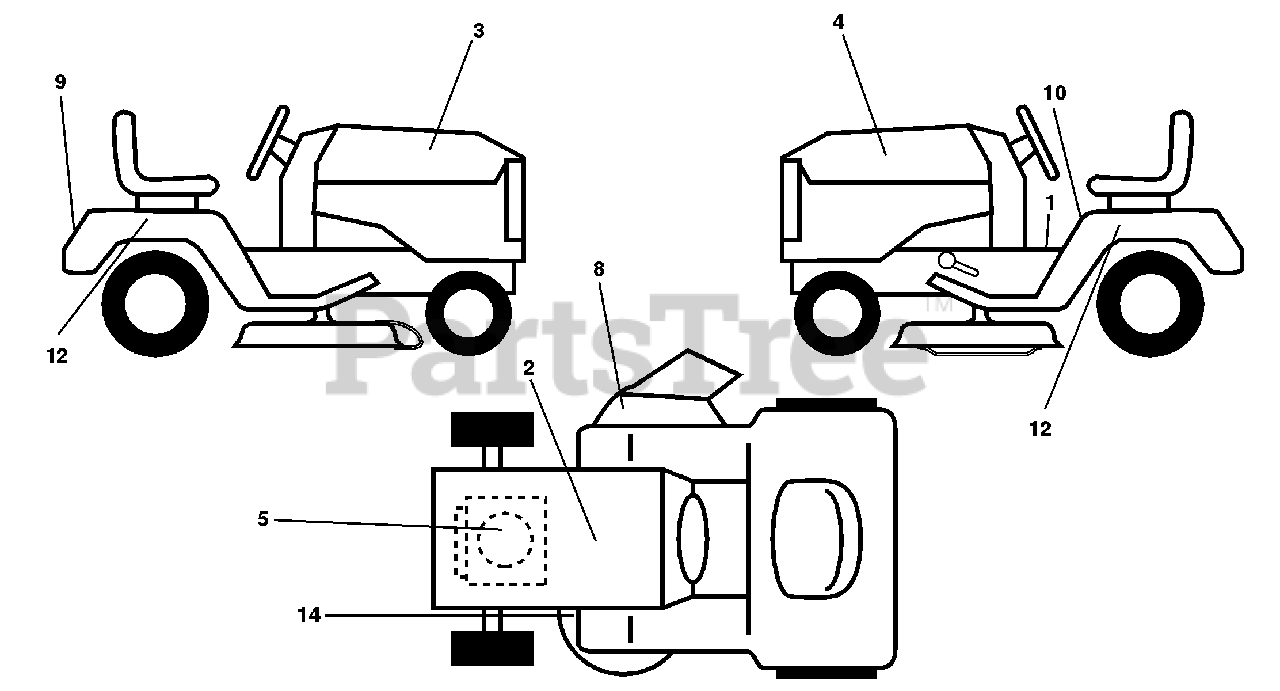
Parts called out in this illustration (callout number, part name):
1	Decal Oper. Step Thru E/F
2	Decal Battery
3	Decal Hood RH
4	Decal Hood LH
5	Decal HP Engine
8	Decal Warning Multi-Languages
9	Decal Fender Husq
10	Decal Fender Danger E/F
12	Decal Fender Auto Husq Radius
14	Decal V-Belt Schematic
